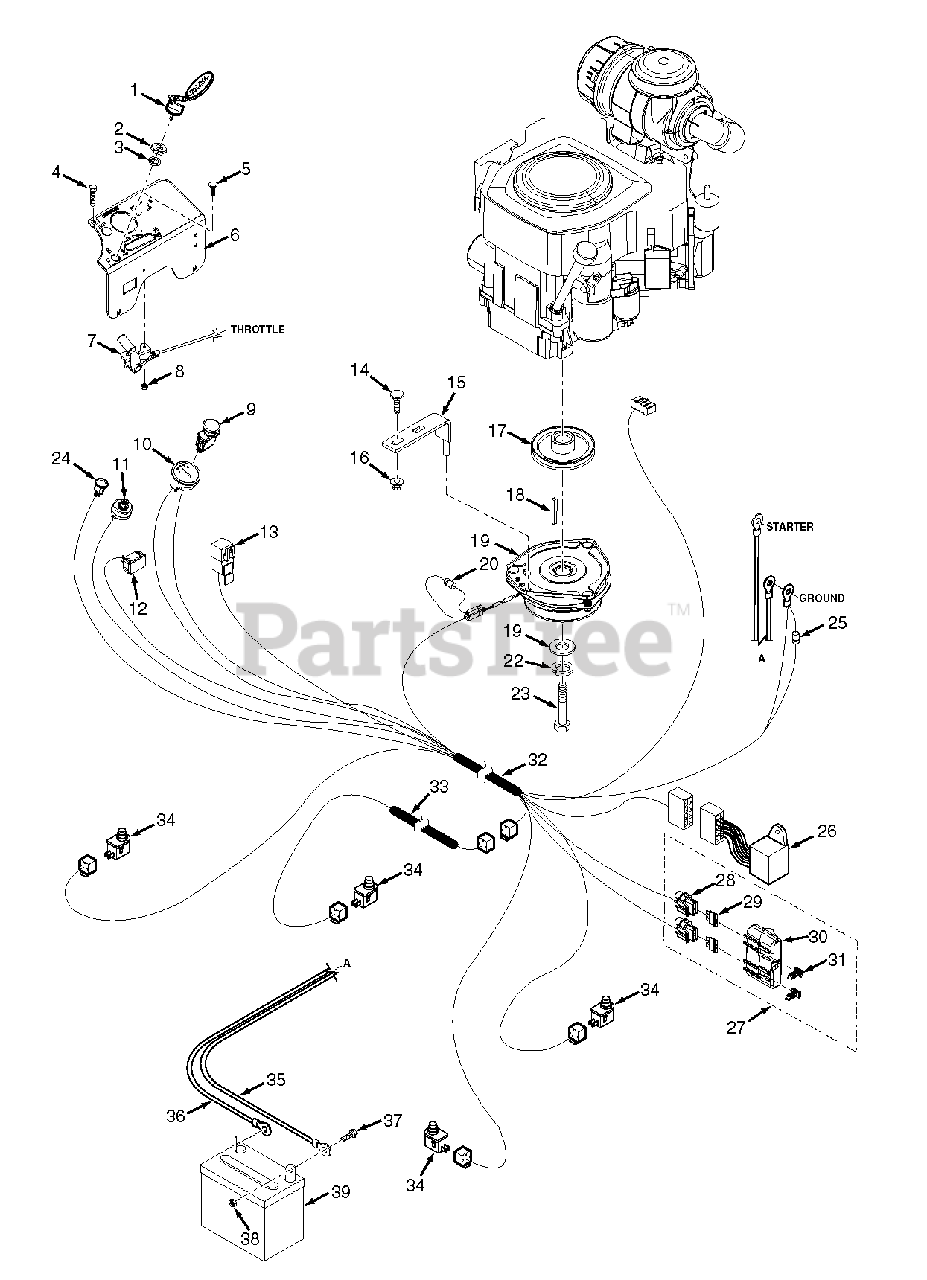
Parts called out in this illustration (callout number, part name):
1	Key, Ignition
1	Key Assembly w/Fob
2	Nut, Hex 5/8-32
3	Lockwasher, 5/8" Internal
4	Bolt, Hex Head Serrated Flange 1/4-20 x 1/2"
5	Bolt, Carriage #10-24 x 1/2"
6	Instrument Panel w/Decal
7	Control Cable
8	Locknut, #10-24
9	Switch, PTO
10	Voltmeter
11	Switch, Starter
12	Hourmeter
13	Relay
14	Bolt, Carriage 5/16-18 x 3/4"
15	Anti-Rotation Weldment
16	Nut, Flange Elastic Stop 5/16-18
17	Pulley, 5" Dia. - 1.125 Bore
18	Key, 1/4 x 1/4 x 3-1/2"
19	Clutch, GT3.5 - 1.125 Bore
20	Diode, 600V - 6A
21	Flatwasher, 7/16-.469 x 1.75 x .25
22	Lockwasher, 7/16" Spring
23	Bolt, Hex Head 7/16-20 x 2-1/4" w/Patch
24	Indicator Light
25	Diode
26	Electronic Module
27	Double Fuse Assy.
28	Fuse Holder
29	Fuse, 20 Amp
30	Cover, Sealed Double
31	Clip, Wire
32	Wire Harness, SCZ-EFI
33	Wire Harness, Operator Platform
34	Switch
35	Battery Cable, 25" Red (Kawasaki)
36	Battery Cable, 27" Black
37	Bolt, Hex Head 1/4-20 x 1/2"
38	Nut, 1/4-20 UNC
39	Battery, 350 CCA
